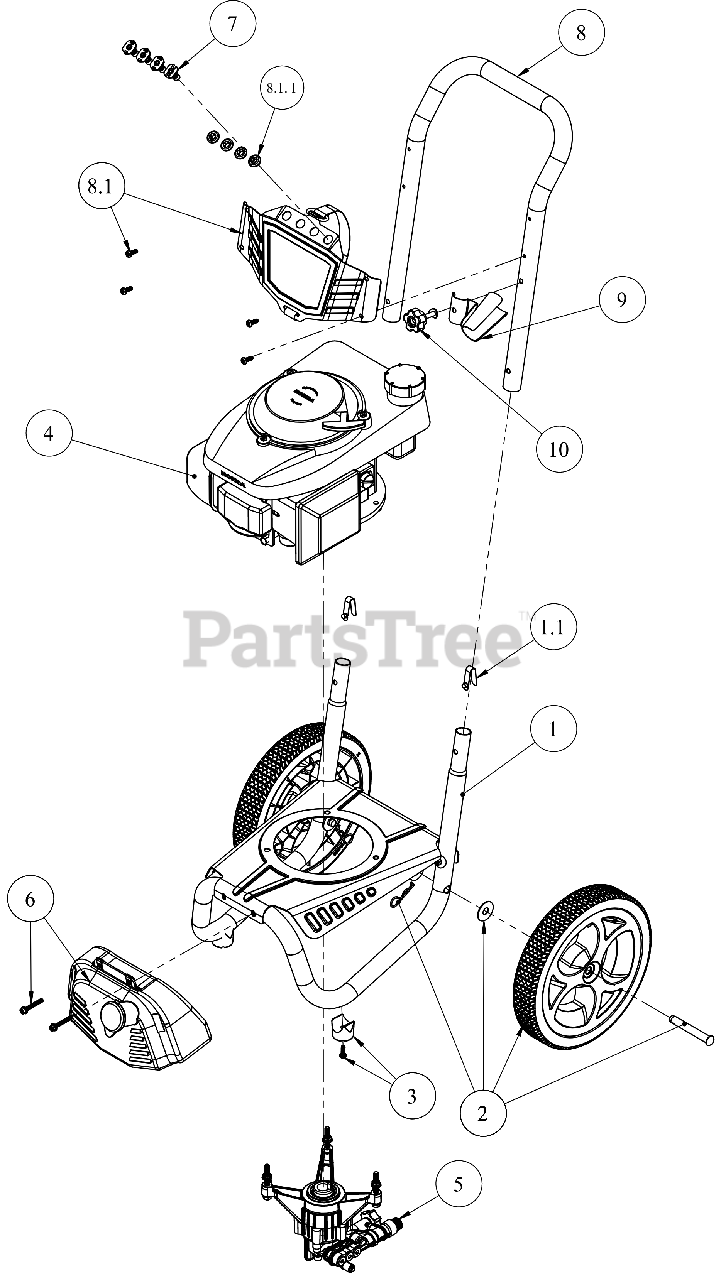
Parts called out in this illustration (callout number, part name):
1	FRAME BASE (YELLOW)
1.1	HANDLE SNAP BUTTON
2	WHEEL KIT-12"
3	FOOT PAD KIT
4	COMPLETE ENGINE
5	PUMP (SVC 510020)
6	SOAP TANK (W/LBL)
7	4 PIECE NOZZLE SET
8	UPPER HANDLE (YELLOW)
8.1	DASHBROARD PANEL (W/LABEL)
8.1.1	SPRAY NOZZLE HOLDER
9	SPRAY GUN HOLDER
10	KNOB-HANDLE MTG
